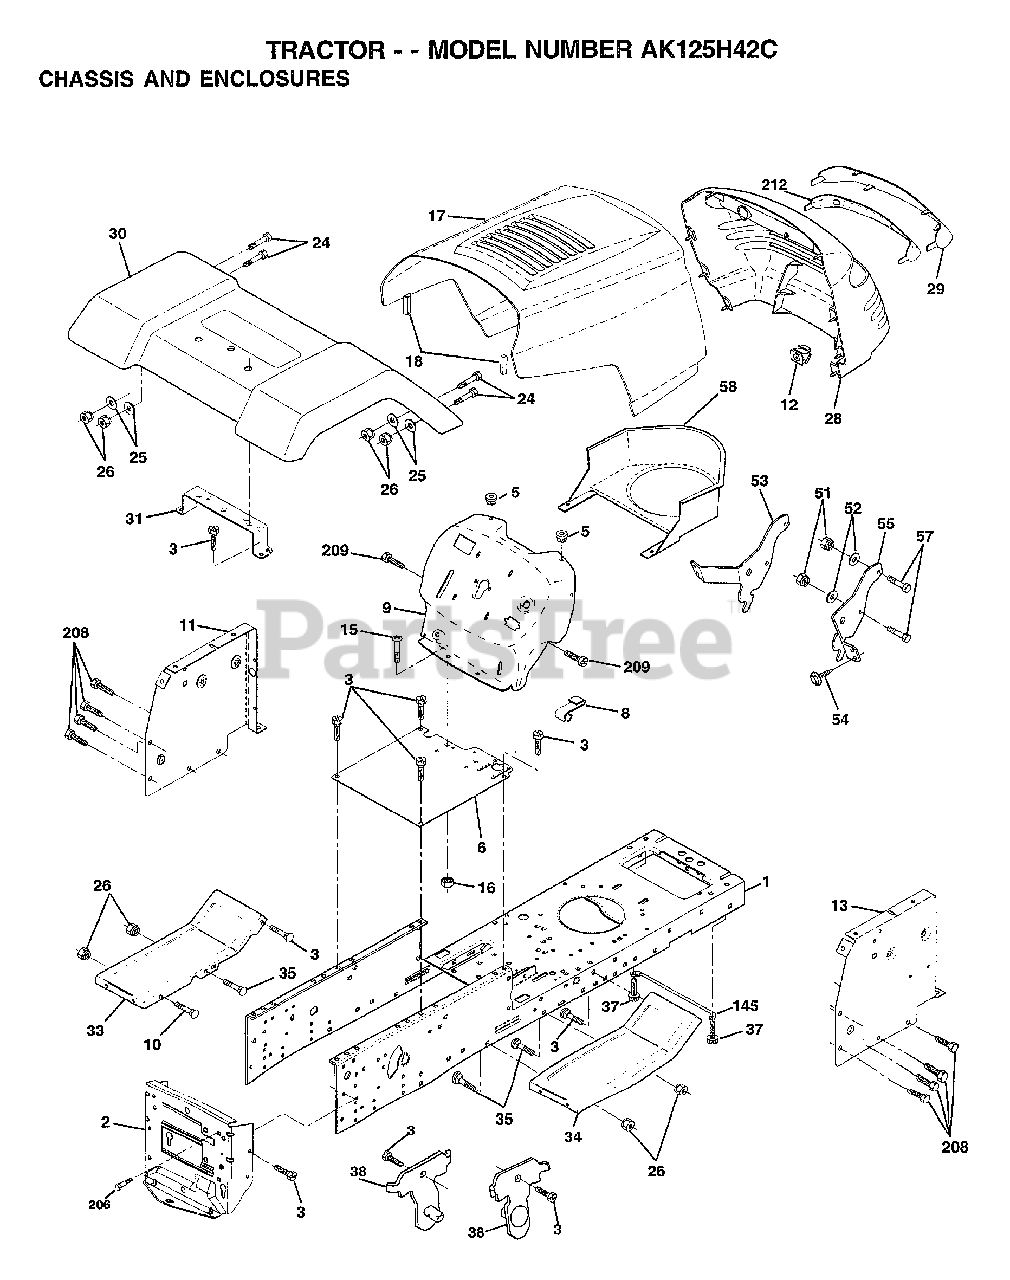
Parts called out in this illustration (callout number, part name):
2	DRAWBAR
3	SCREW
5	BUMPER-HOOD/DASH
6	SADDLE
8	CLIP.RETAINER
9	DASH
11	"PANEL-DASH,LH"
12	CLIP.TINNERMAN
15	SCREW
17	HOOD.STEEL.ASSY
24	BOLT
25	WASHER
26	NUT
28	GRILL.BLK
29	LENS.GRILLE.PRIVATE LABEL
31	BRKT FENDER
33	FOOTREST LH
34	FOOTREST RH
35	BOLT
37	SCREW LT
38	BRKT ASM PIVOT MOWER REAR
51	NUT
52	WASHER
53	BRACKET.GRILLE.LH
54	SCREW.HEX.WS.HD
55	BRACKET.GRILLE.RH
58	AIR DUCT
145	"ROD POVOT,CHASSIS"
206	BOLT SHOULDER
208	SCREW
209	SCREW
212	INSERT LENS REFLECT
